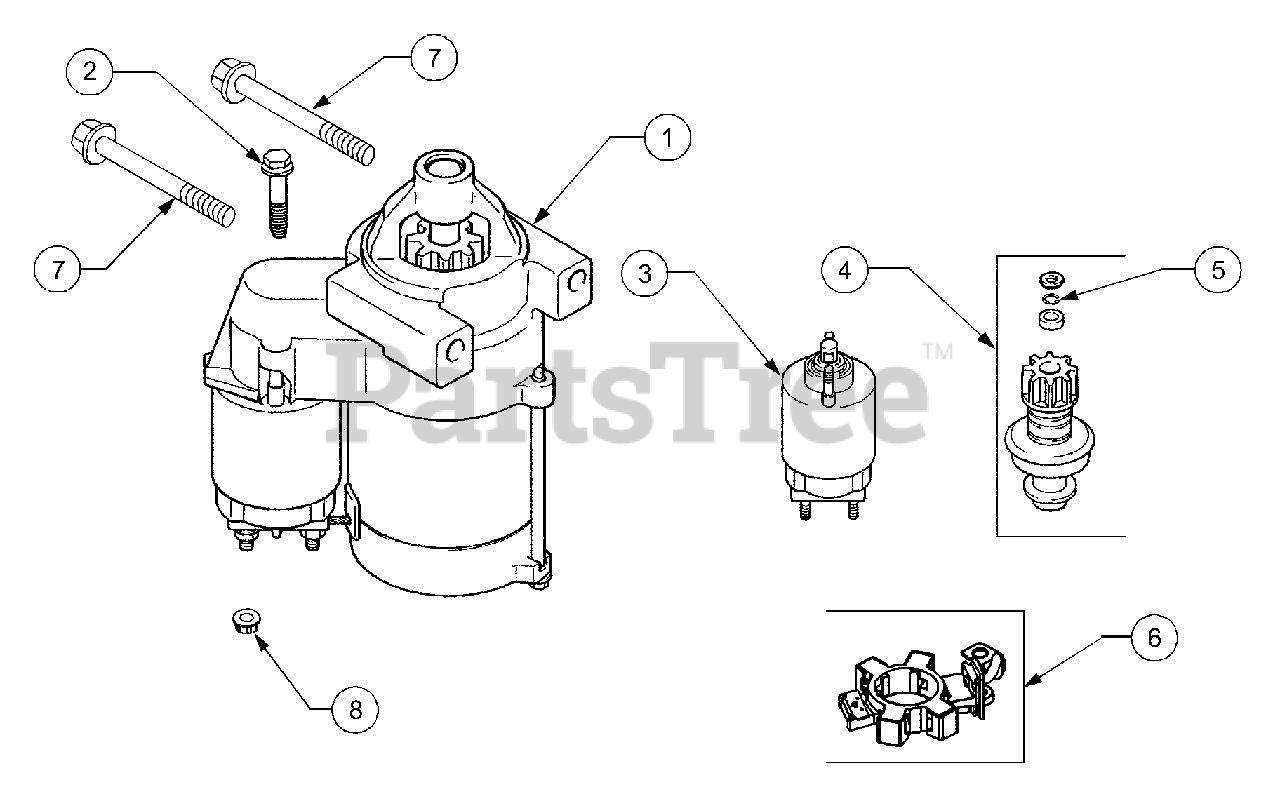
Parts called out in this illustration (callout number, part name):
1	Starter,
2	Screw, External Torx Hd.
3	Kit, Solenoid
4	Kit, Pinion Drive
7	Screw, Hex Flange, M8 x 1.25 x 80
8	Nut, Hex Flange, M8 x 1.25
